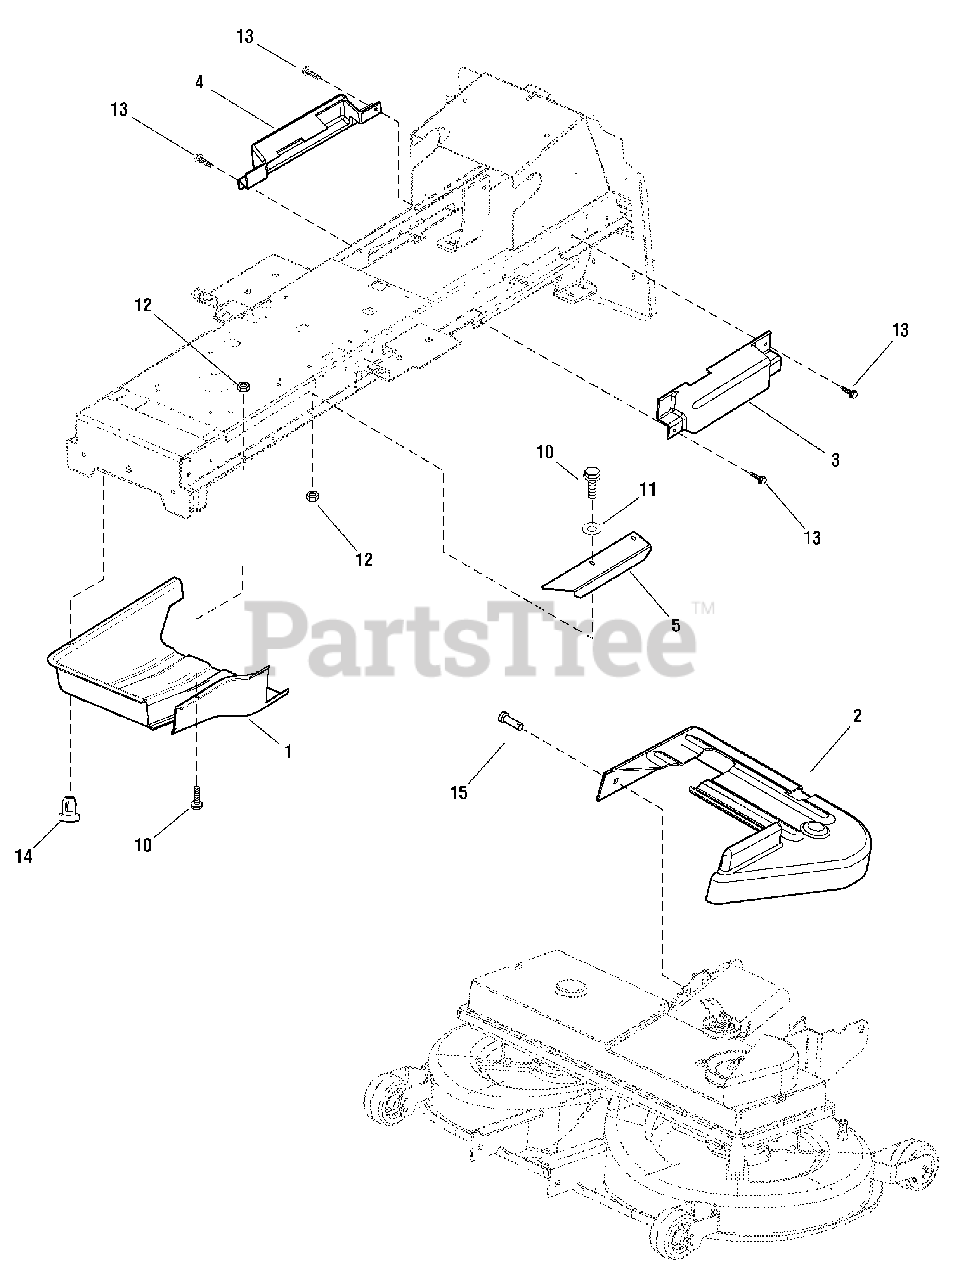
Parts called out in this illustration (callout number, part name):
1	COVER, Clutch
2	COVER, Mower Deck
3	COVER, Roller, Left
4	COVER, Roller, Right
5	COVER, Side
10	SCREW, M5 x 12
12	NUT, M5
13	SCREW, ST, 5.5 x 19
14	HOUSING
